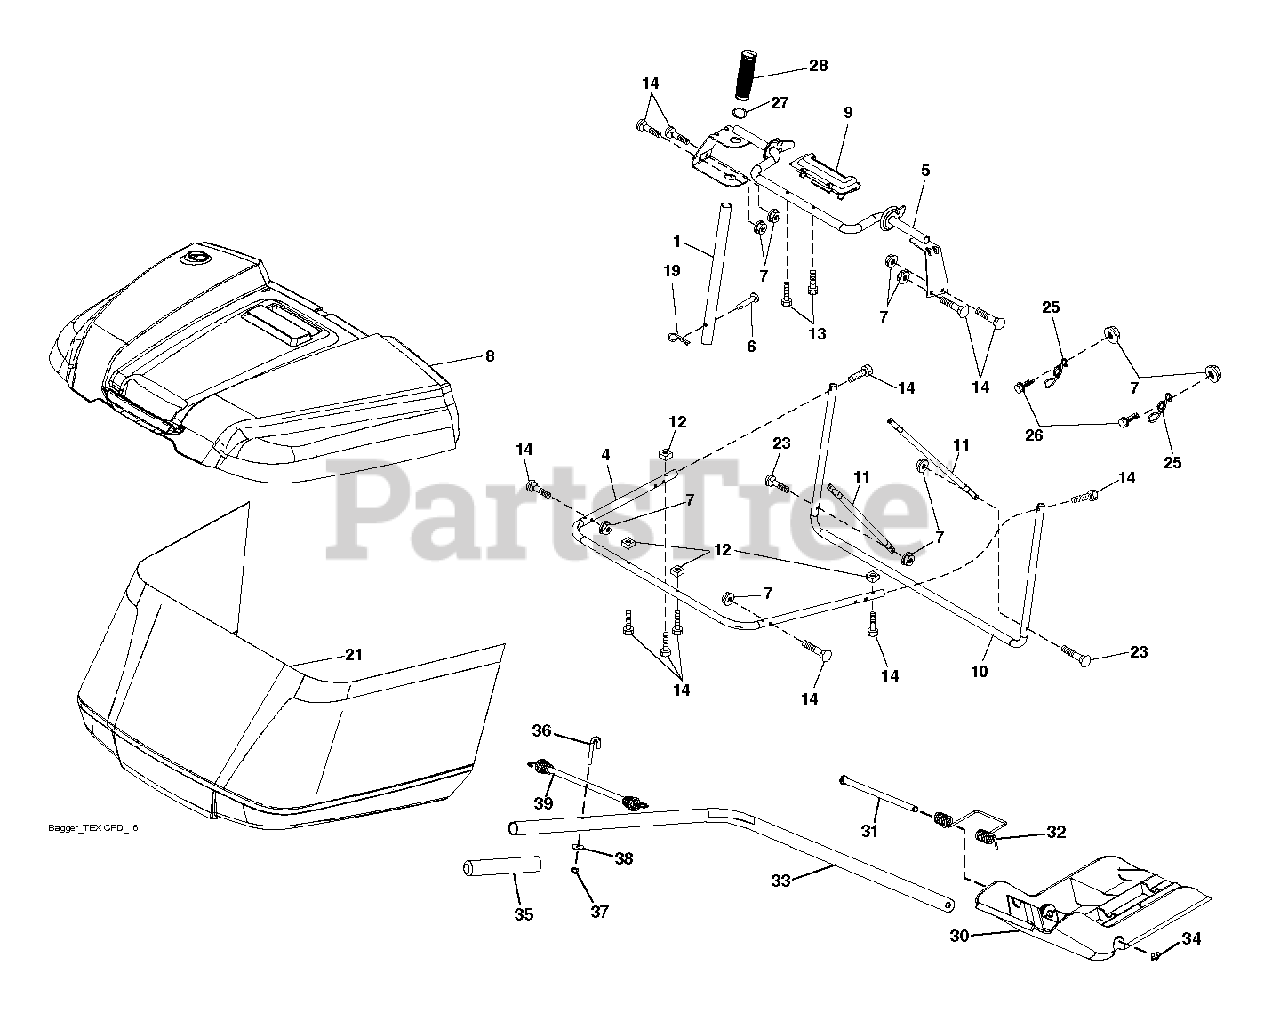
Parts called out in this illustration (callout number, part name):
1	TUBE.PNT.HDL.BAGGER.
6	RIVET,DRILLED
7	NUT T
19	PIN.COTTER.5/16.BOW TI
26	SCREW HEX CRT
28	GRIP.HANDLE.BLACK
34	E-RING.5/16"
38	WASHER
